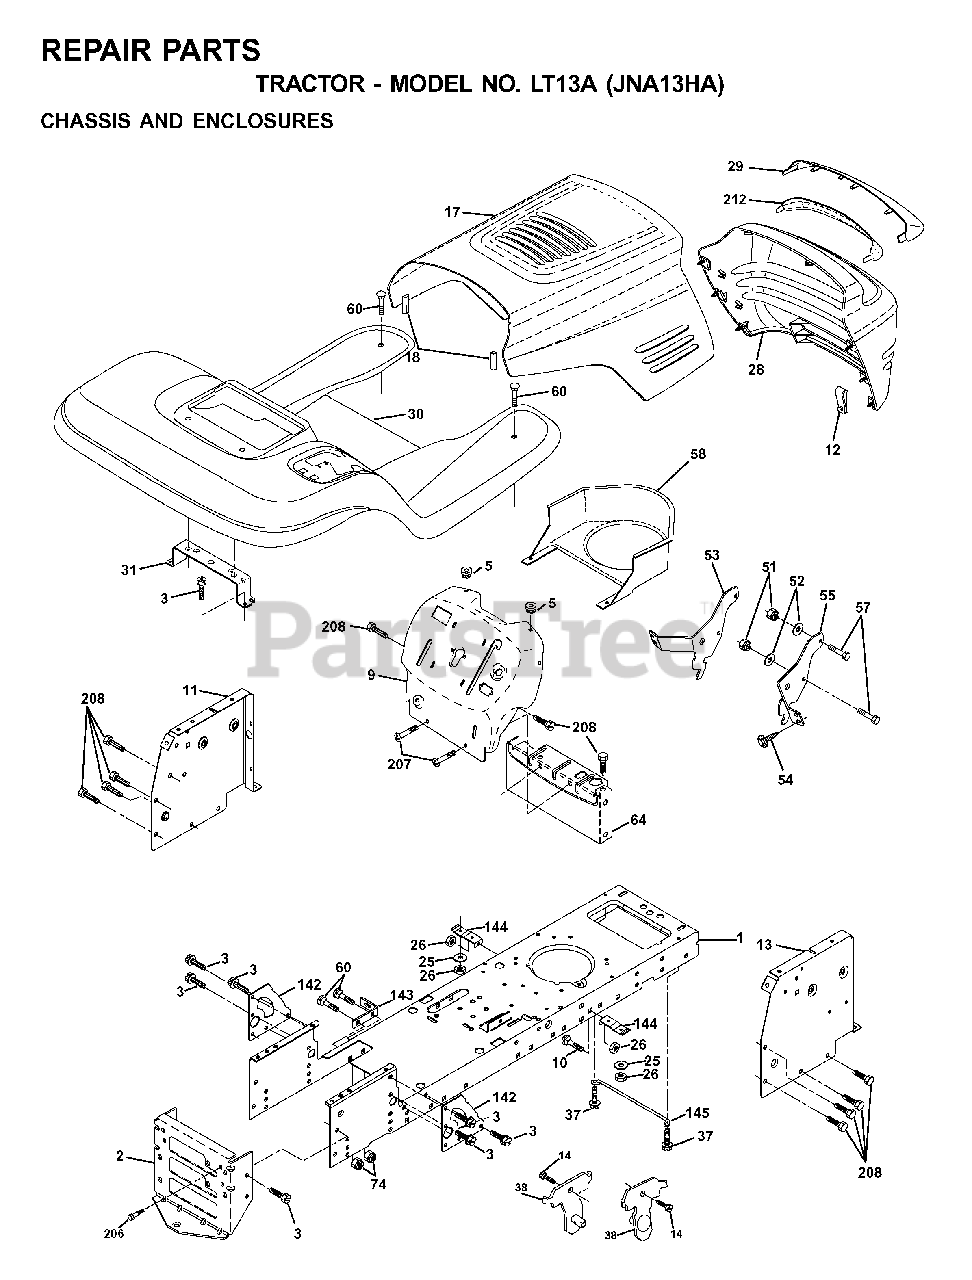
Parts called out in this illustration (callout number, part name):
1	CHASSIS STAMPING
2	DRAWBAR, 12GA
3	SCREW 3/8-16X3/4
5	BUMPER.RUBBER.HOOD
10	BOLT D
11	PANEL DASH LH
13	PANEL DASH RH
18	BUMPER HOOD T
25	WASHER
26	NUT
38	BRACKET
51	LOCKNUT
53	BRACKET.GRILLE.LH
57	BOLT
58	AIR DUCT P/L/LT
64	DASH LOWER
74	LOCKNUT
142	PLATE
143	BRACKET, SWAY BAR
144	BRACKET FOOTREST
145	ROD PIVOT CHASSIS/HOOD
206	SHOULDER BOLT 5/16-18TT
207	SCREW, 5/16-18 X 1/2
208	SCREW 3/8-16X1/2
